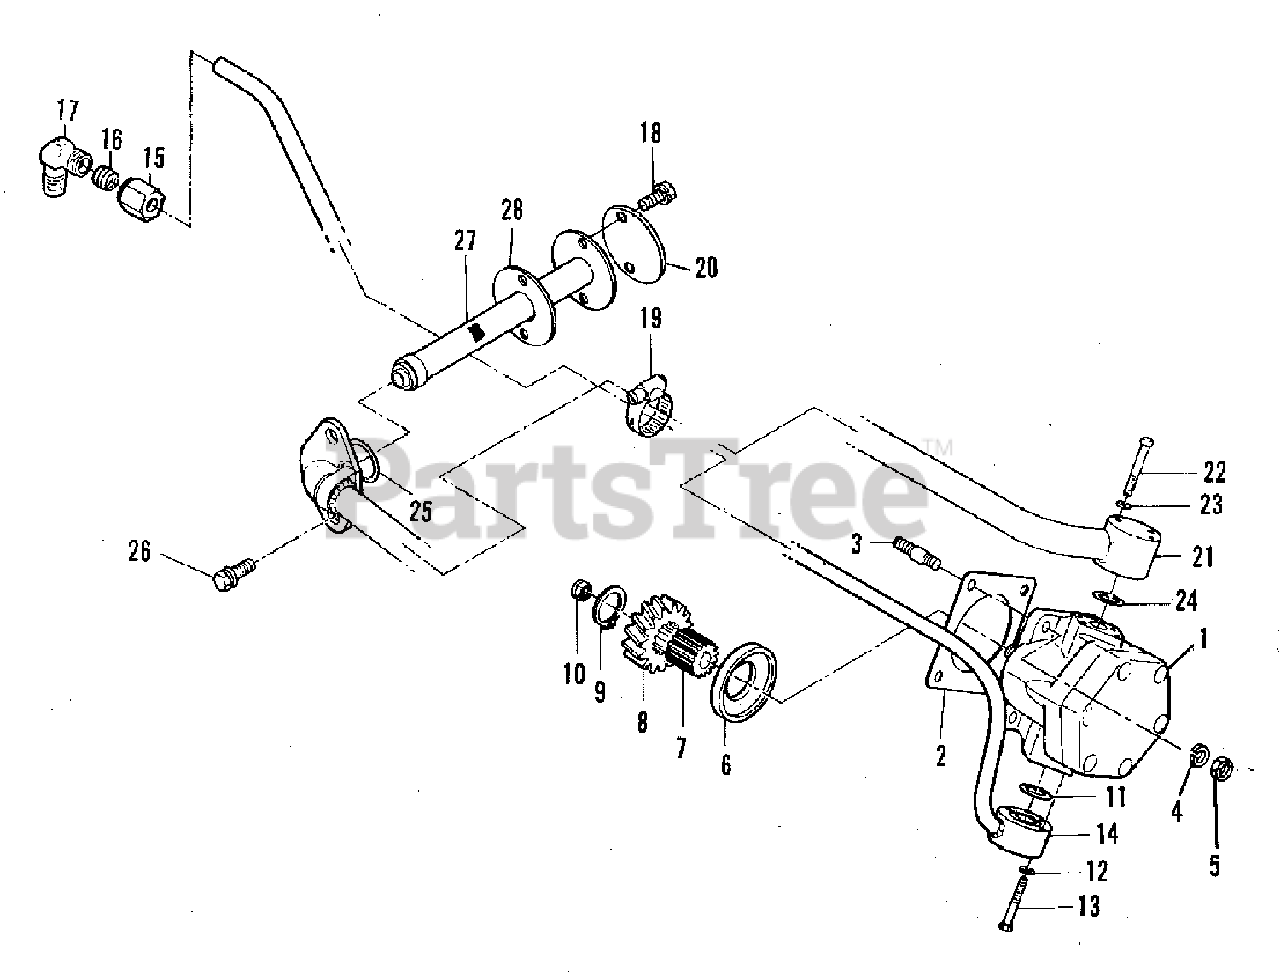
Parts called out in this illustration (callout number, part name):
1	PUMP, hydraulic (Refer to PUMP Group for Components)
3	STUD, M8 X 31
4	LOCKWASHER, M8
6	WASHER, thrust
7	SHAFT, hydraulic pump drive
9	RING, snap
12	LOCKWASHER, M6
14	TUBE ASSEMBLY, delivery (Incl. Items 15 & 16)
15	NUT, tube
18	CAPSCREW, M8 x 20
20	CAP, strainer
21	TUBE, suction
23	LOCKWASHER, M6
26	CAPSCREW, M8 x 25
28	GASKET, strainer
